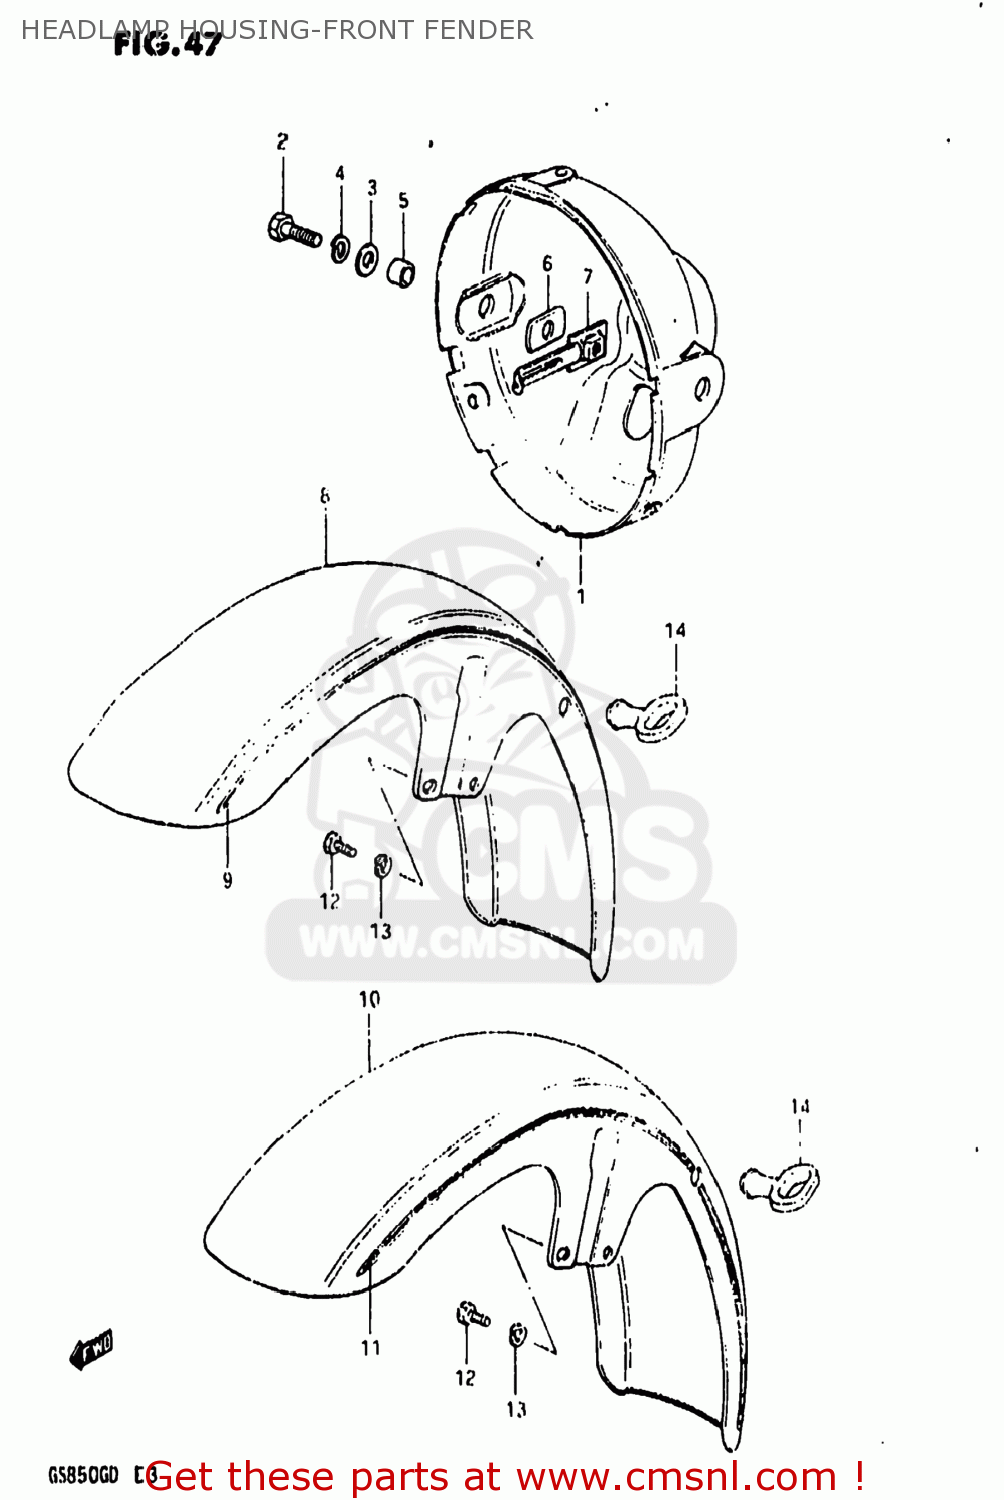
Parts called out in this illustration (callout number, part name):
1	HOUSING,HEADLAMP
2	BOLT
3	WASHER
4	LOCK WASHER
5	SPACER (8.8X12X7)
6	CUSHION
7	PLATE,HEADLAMP HOUSING
8	FENDER,FRONT
9	TAPE,FRONT FENDER
10	FENDER,FRONT
11	TAPE,FRONT FENDER
12	BOLT
13	LOCK WASHER
14	GUIDE,CABLE
